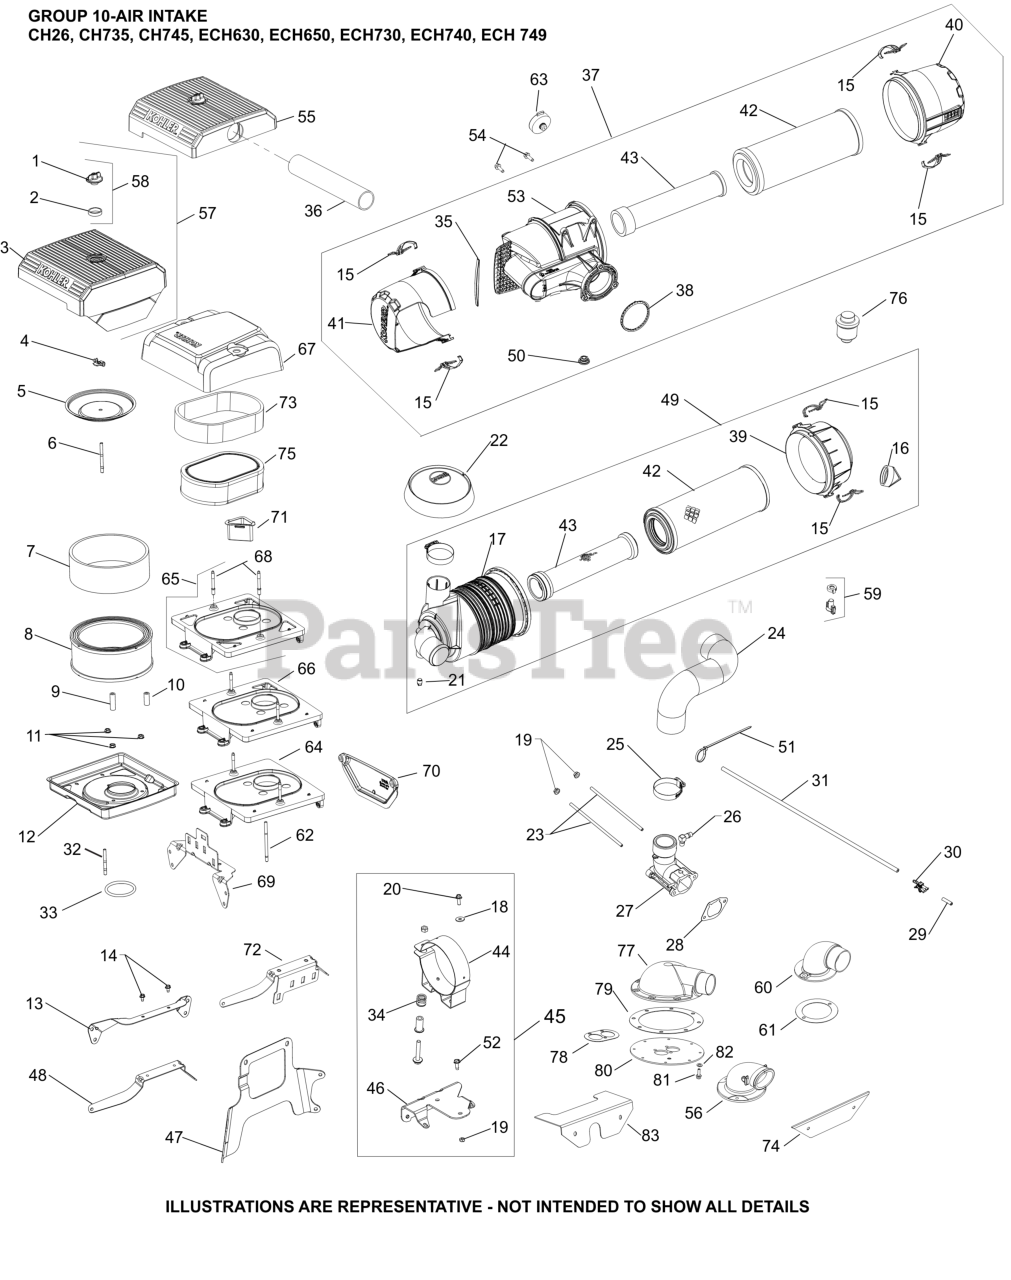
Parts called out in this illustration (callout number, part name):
11	NUT, FLG M6X1.0
12	BASE, AIR CLEANER
15	CLIP ASSEMBLY
29	CAP, MASKING
30	CONNECTOR, EVAPORATIVE
35	DAMPER, FOAM INSERT
37	FILTER, AIR ASSY W/BREATHER HOLE
38	O-RING (HDAC SEAL-EFI)
40	COVER, AIR FILTER
41	COVER, RAIN CAP
42	ELEMENT, AIR FILTER - PRIMARY
43	ELEMENT, AIR FILTER - SAFETY
48	AIR CLEANER BRACKET
50	PLUG, HOLE
54	SCREW, THREAD FORMING
